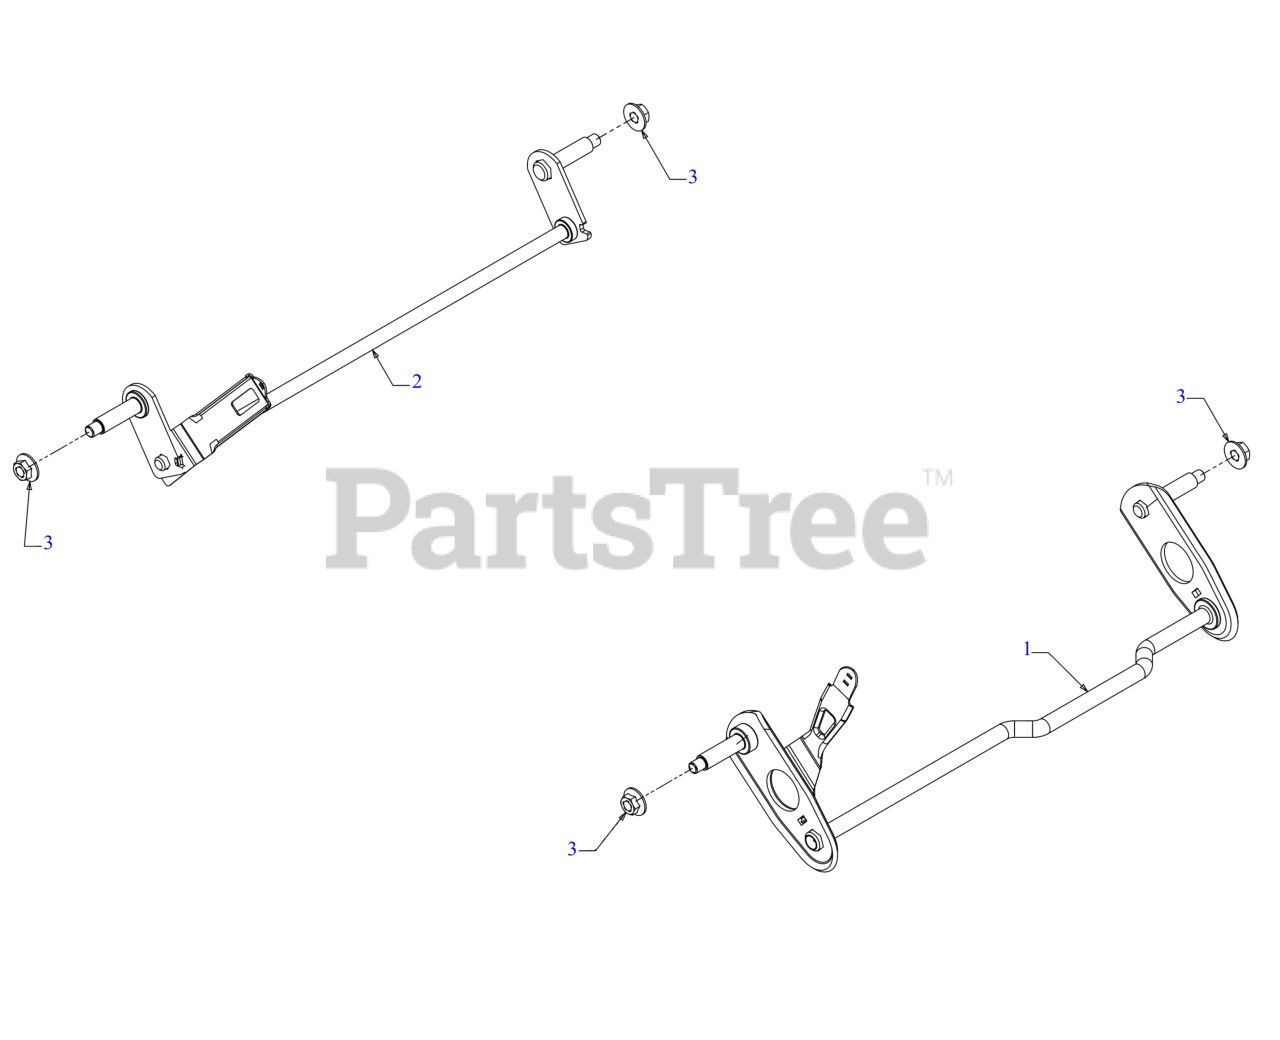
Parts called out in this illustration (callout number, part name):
1	FRONT AXLE ASSEMBLY
2	8" REAR AXLE ASSEMBLY
3	FLANGE LOCK NUT
